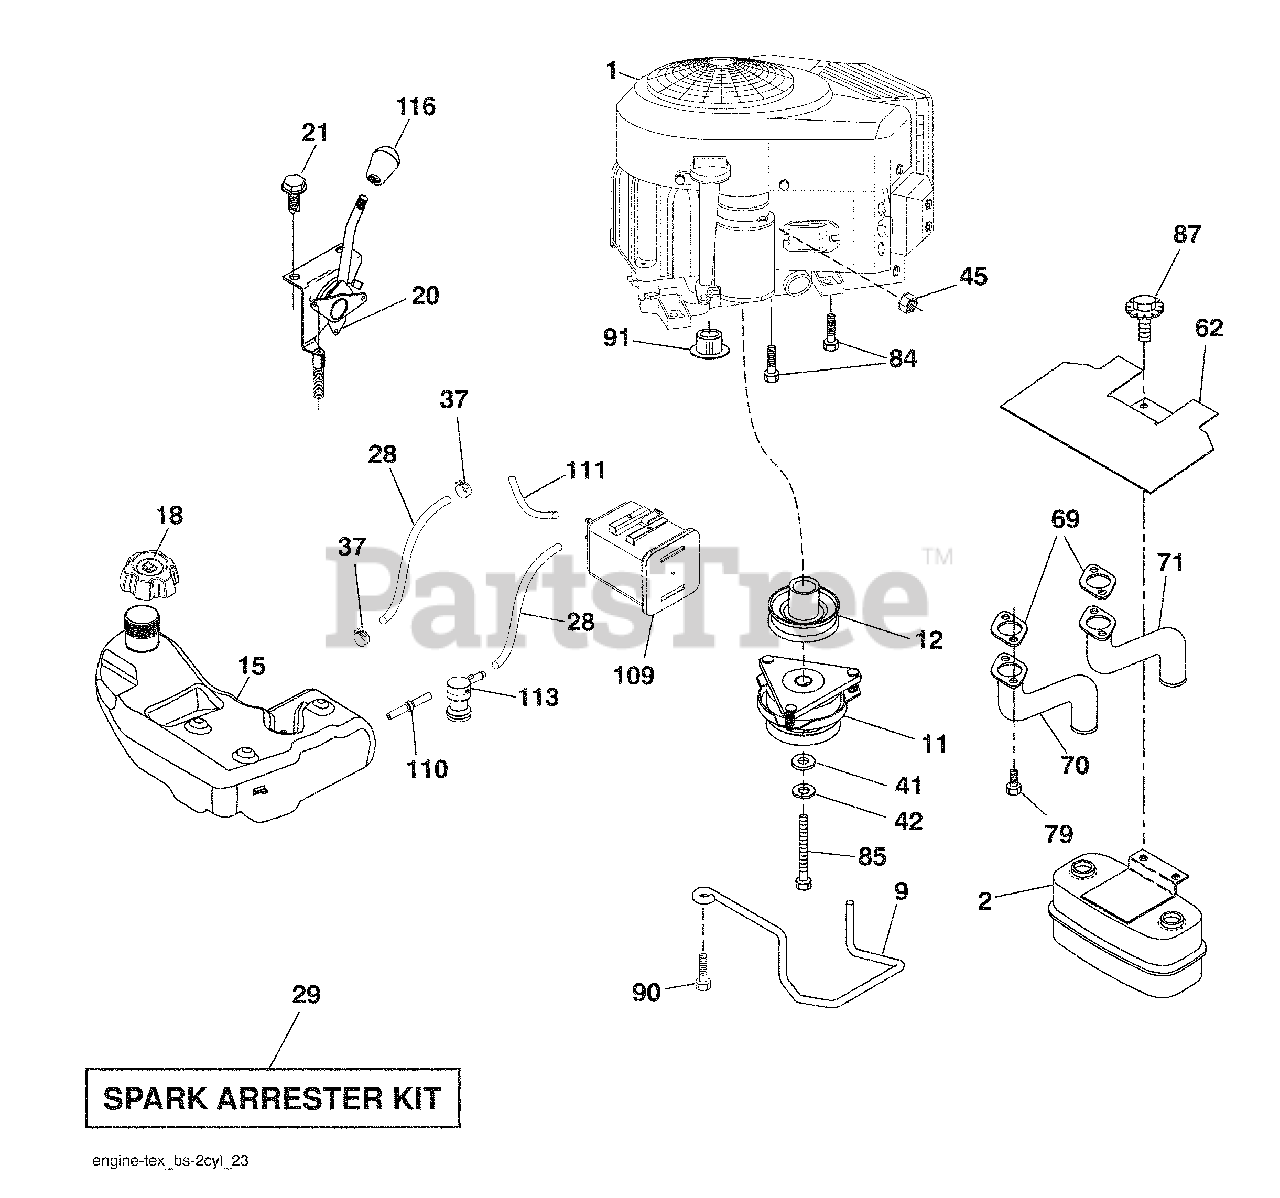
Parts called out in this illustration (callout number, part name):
9	Keeper Belt Engine
11	Clutch Electric
12	Pulley Engine
18	Cap Asm
20	Control Throttle
21	Screw #10 x 0.750
28	Fuel Line
29	Spark Arrester Kit
37	Clamp Hose
41	Washer 1-1/2 OD x 15/32 ID x .250
42	Washer Lock 7/16
45	Nut Keps Hex 1/4-20 unc
62	Shield Heat Muffler
70	Tube Exhaust LH
71	Tube Exhaust RH
79	Screw Socket Head 5/16-18 x 1
84	Screw 3/8-16 x 1-1/4
85	Bolt Hex 7/16-20 x 3.75 Gr. 5
87	Bolt 5/16-18 unc x 3/4 w/Sems
90	Screw 3/8-16 x 1
109	Canister Carbon Filter Asm.
110	Valve Anti-Slosh
111	Purge Line
113	Valve Slant Cartrdg
116	Knob Soft Touch
